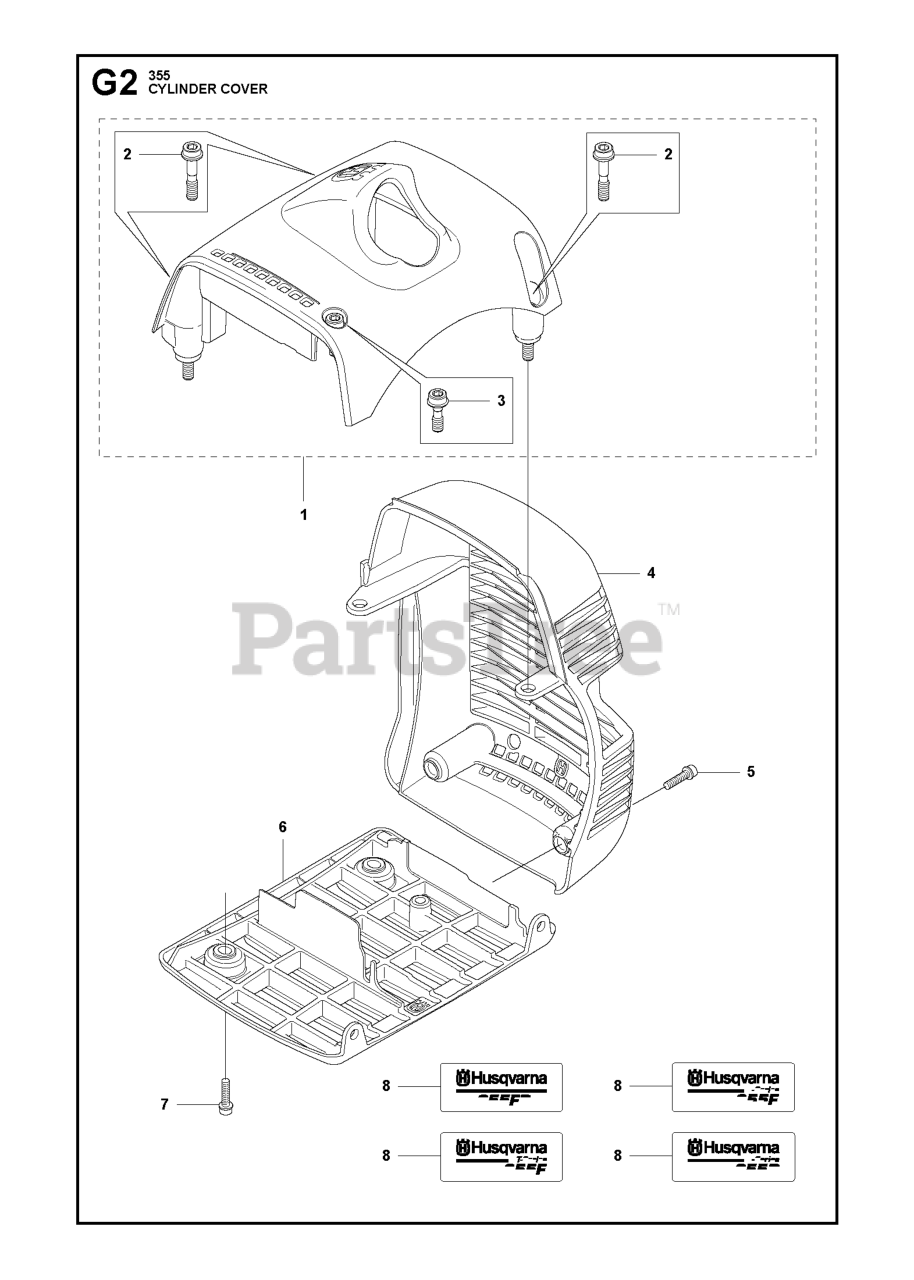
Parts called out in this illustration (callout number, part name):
1	CYLINDER COVER ASSY SPARE PAR
2	SCREW IHSCFMO
3	SCREW IHSCFMO
4	HEAT PROTECTOR
6	PROTECTIVE COVER ASSY HUSQ
8	LABEL
